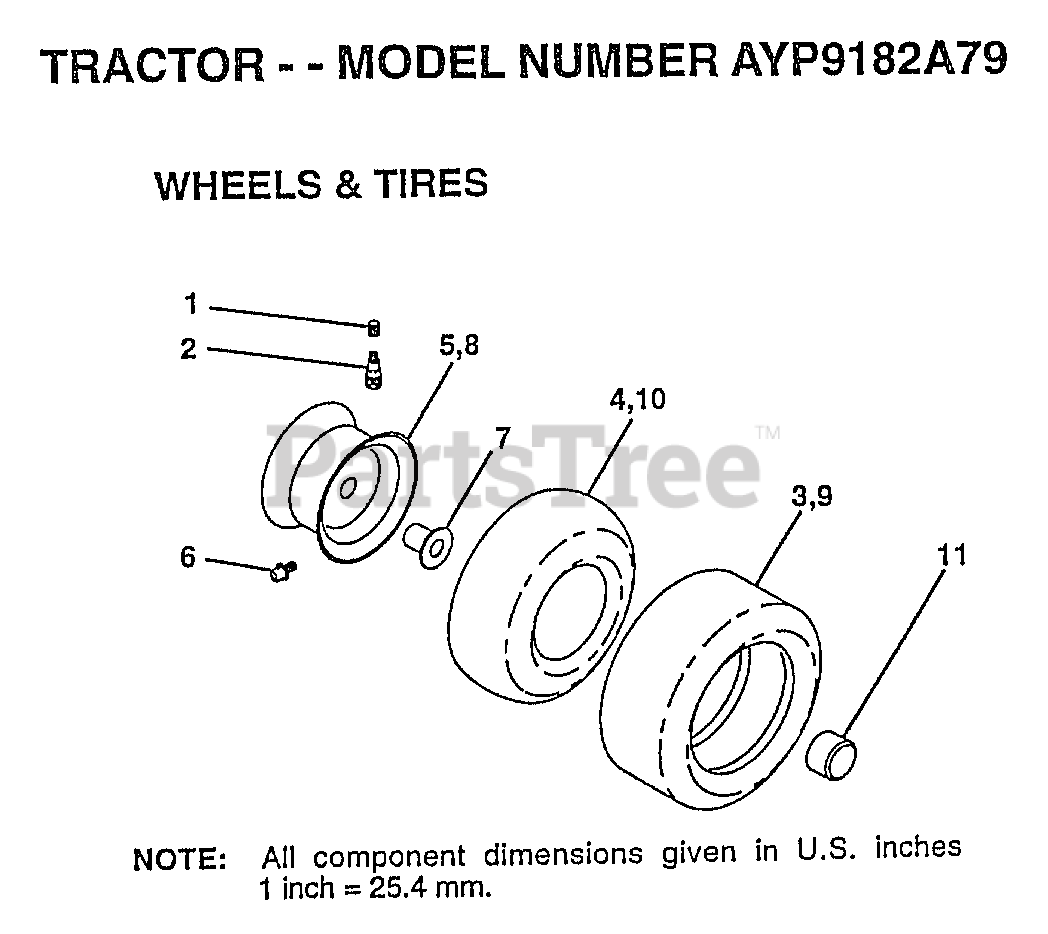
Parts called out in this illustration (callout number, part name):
1	VALVE CAP
2	VALVE STEM LT
4	TUBE.5.3/4.5/6
5	"RIM ASM 6"" FRT"
6	FITTING LT
7	"FLANGE, BEARING"
8	"RIM AS 8"" REAR"
9	TIRE.20X8-8
10	TUBE.18X9.5-8
11	HUB CAP
